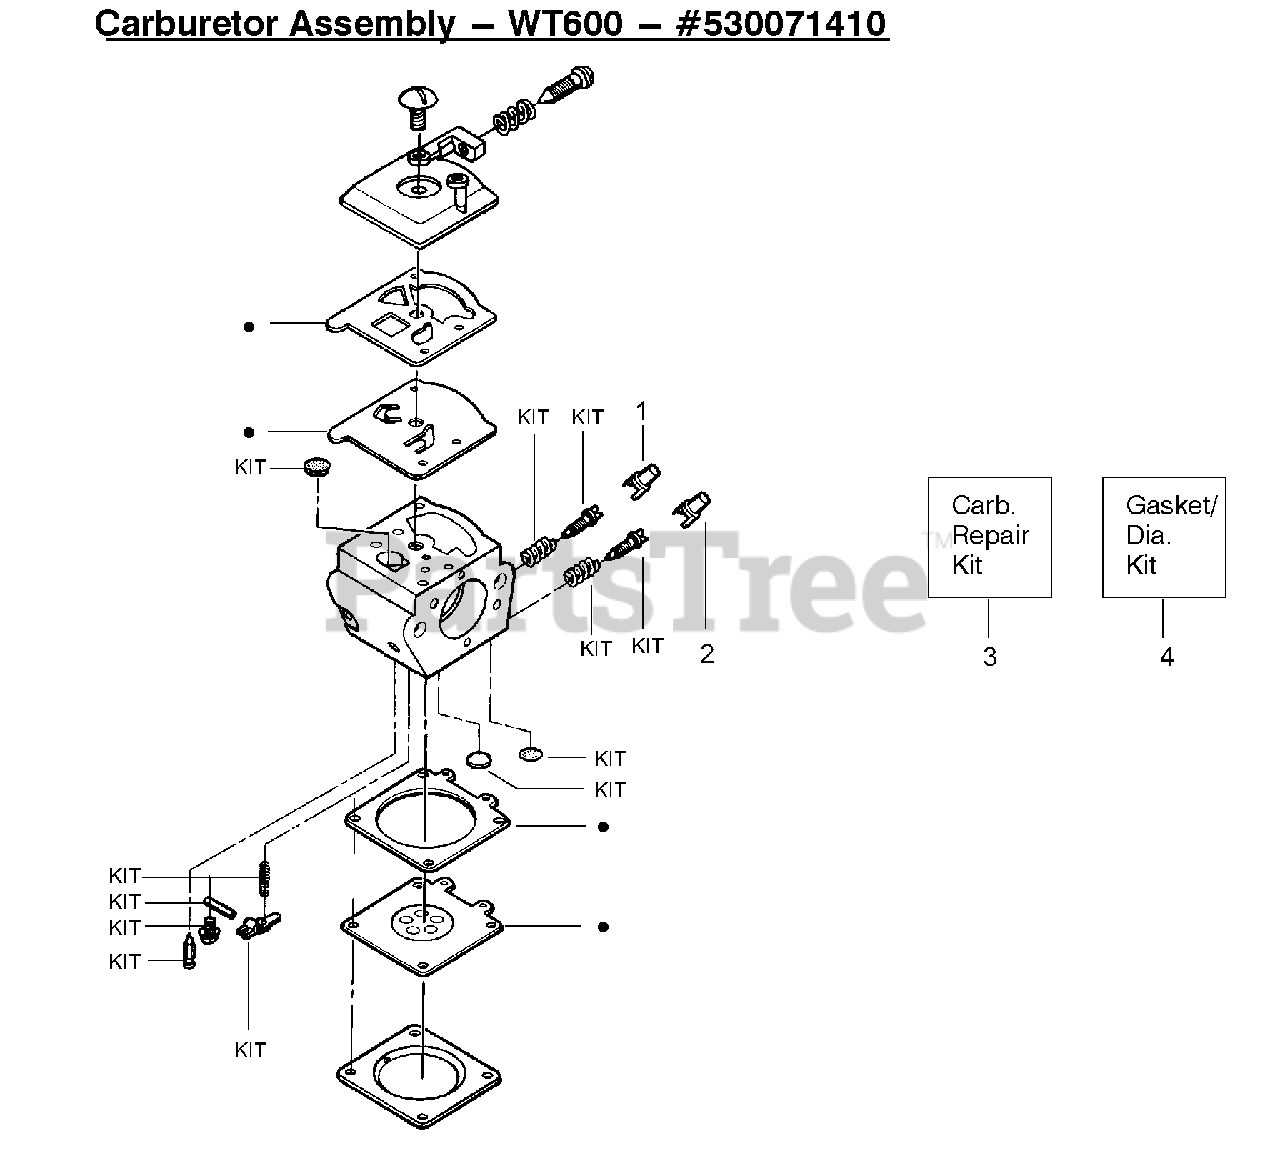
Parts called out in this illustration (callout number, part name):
1	Limiter Cap-High
2	Limiter Cap-Low
3	Carburetor Repair Kit
4	Gasket Diaphragm Kit
530071410	Carburetor Assembly WT600
